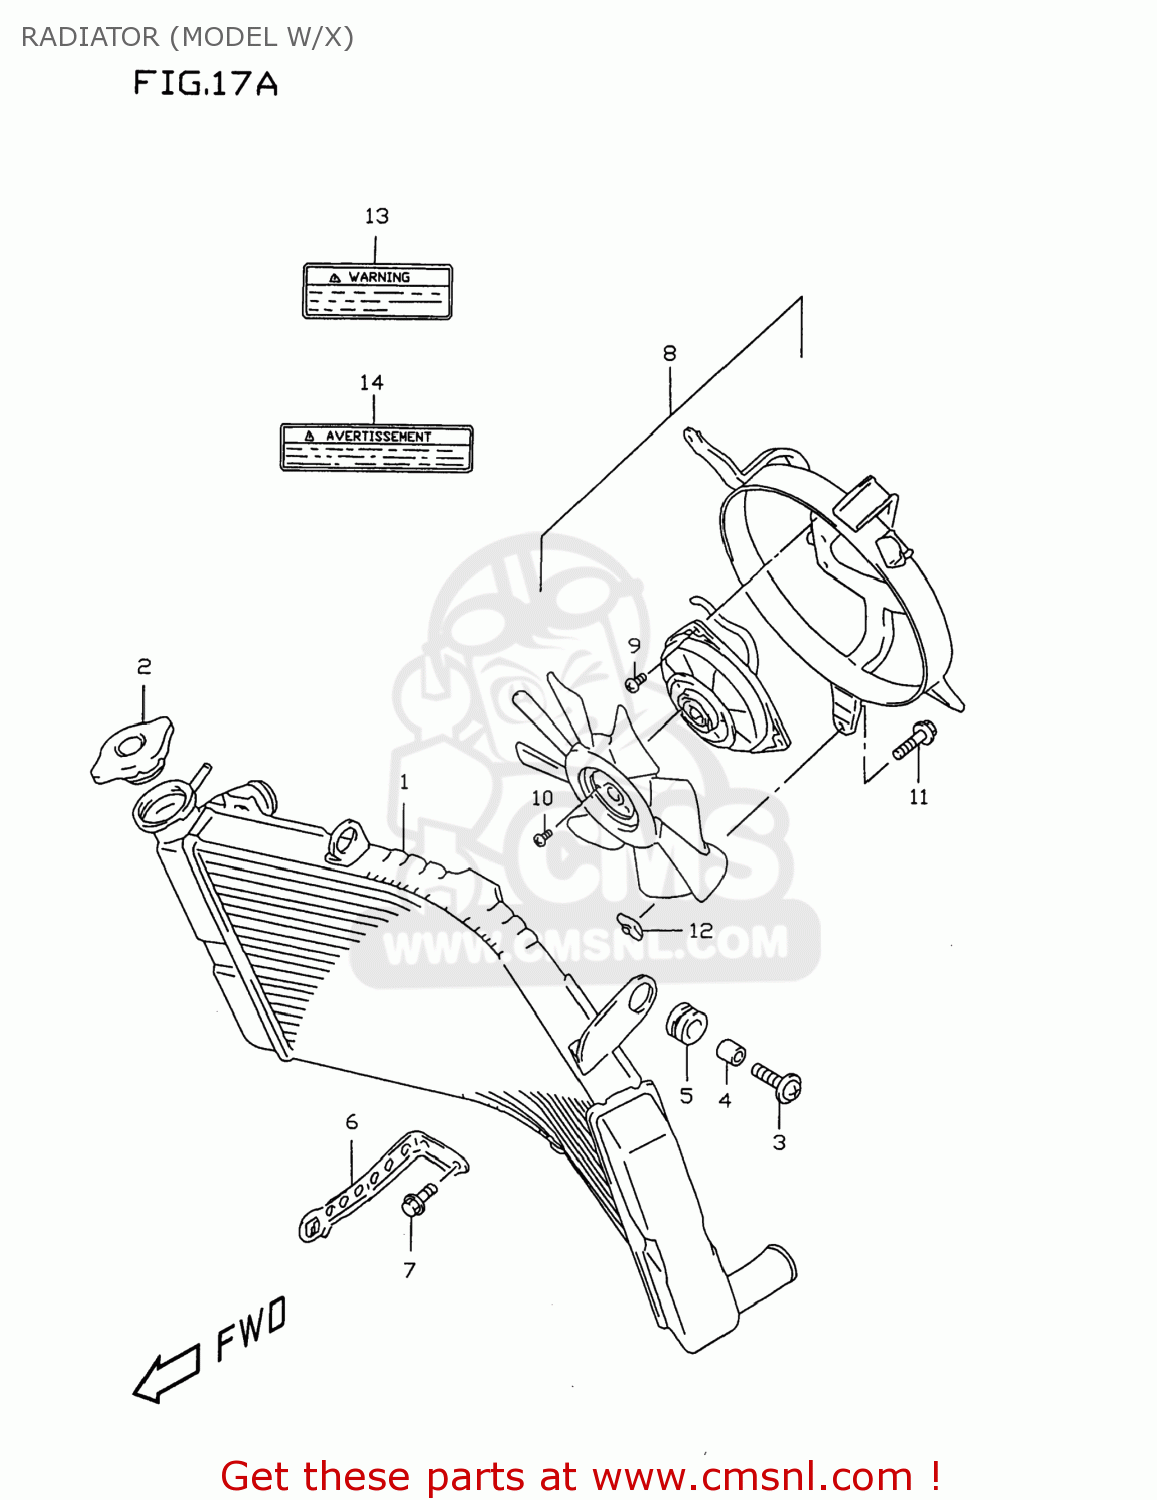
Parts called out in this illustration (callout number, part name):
1	RADIATOR ASSY,WATER
2	CAP,RADIATOR
3	BOLT 6X20
4	SPACER(6.5X10X12)
5	CUSHION
6	BRACKET,RADIATOR LWR
7	BOLT
8	FAN ASSEMBLY,RADIATOR
9	SCREW
10	SCREW 4X6
11	BOLT
12	NUT
13	LABEL (COOLING FAN)
14	LABEL,COOLING FAN
